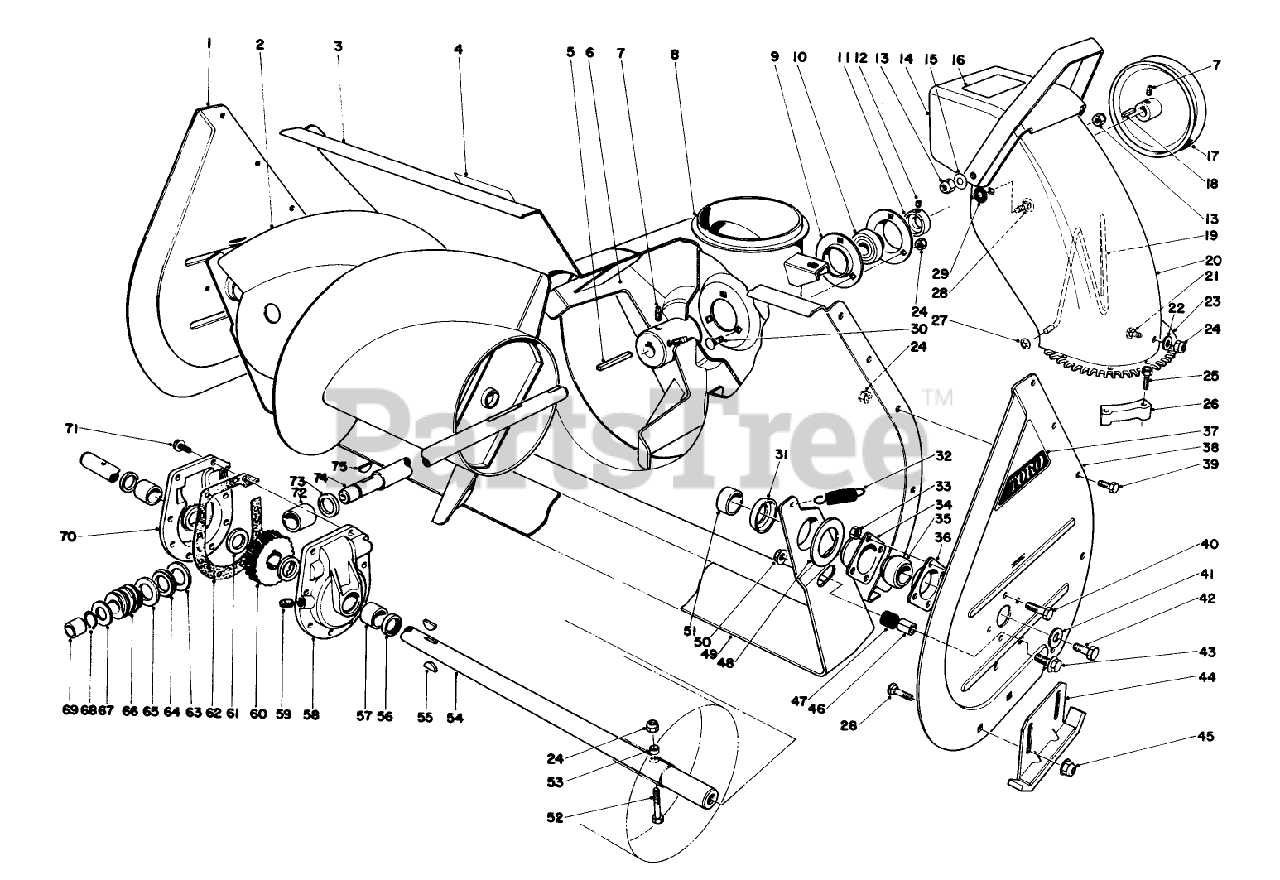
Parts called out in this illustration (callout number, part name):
1	Side Plate
2	RH AUGER WA 26" B
3	AUGER HSG WA 26" R
4	Decal
6	IMPELLER ASM
7	SCREW-SET, SQH
8	CHUTE RING
9	BRG FLANGE
10	BALL BRG W/COLLAR
11	EXT LOCKING COLLAR
12	SCREW-HSH
13	NUT-LOCK, CONE
14	Deflecwor (Incl. Ref. #16)
15	WASHER-BELLEVILLE
16	CHUTE WARNING DECAL
17	1/2 X 9.5 DIA PULLEY
18	SQUARE KEY
19	WIRE-CHUTE
20	Upper Chute
21	SCREW-CARR
22	WASHER-PLAIN
23	Screw
24	NUT-LOCK, CONE
25	SCREW-SPECIAL
26	RETAINER-CHUTE
27	NUT-PUSH
28	SCREW-CARR
29	Rubber Washer
30	BOLT-CARR
31	Positioner-Scraper
32	SPRING-TENSION
34	BEARING-FLANGE, FRONT
35	BEARING
36	BEARING-FLANGE, REAR
37	AUGER SIDE PLT DECAL
38	Side Plate L. H.
39	SCREW-HH
40	SCREW-HH
41	WASHER
42	SCREW-HH
43	SCREW-HHF
44	AUGER SKID WA R
45	NUT-HHF, WHIZ
46	SCRAPER STOP SPACER
47	SCRAPER STOP CUSHION
48	SCRAPER BLADE SPACER
49	SCRAPER BLADE 26 R
50	NUT-HF
51	AUGER SPACER
52	Auger Bolt
53	SPACER-HUB, AUGER
54	26 AUGER SHAFT
55	KEY-WOODRUFF
56	SEAL-OIL
57	BUSHING
58	Gear Case Assembly L.H. (Incl. Ref. #56 & 57)
59	PLUG-PIPE, SQH
60	GEAR-WORM, 27T
61	WASHER-THRUST
62	Gasket
63	WASHER-THRUST
64	BEARING-THRUST
65	THRUST-WASHER
67	WASHER-THRUST
68	Ring-Snap
69	BUSHING
70	Gear Case Assembly R.H. (Incl. Ref. #56 & 57)
71	SCREW-HWHTF
72	BUSHING-SPECIAL
73	RING-QUAD
74	SHAFT-IMPELLER
75	KEY-WOODRUFF
